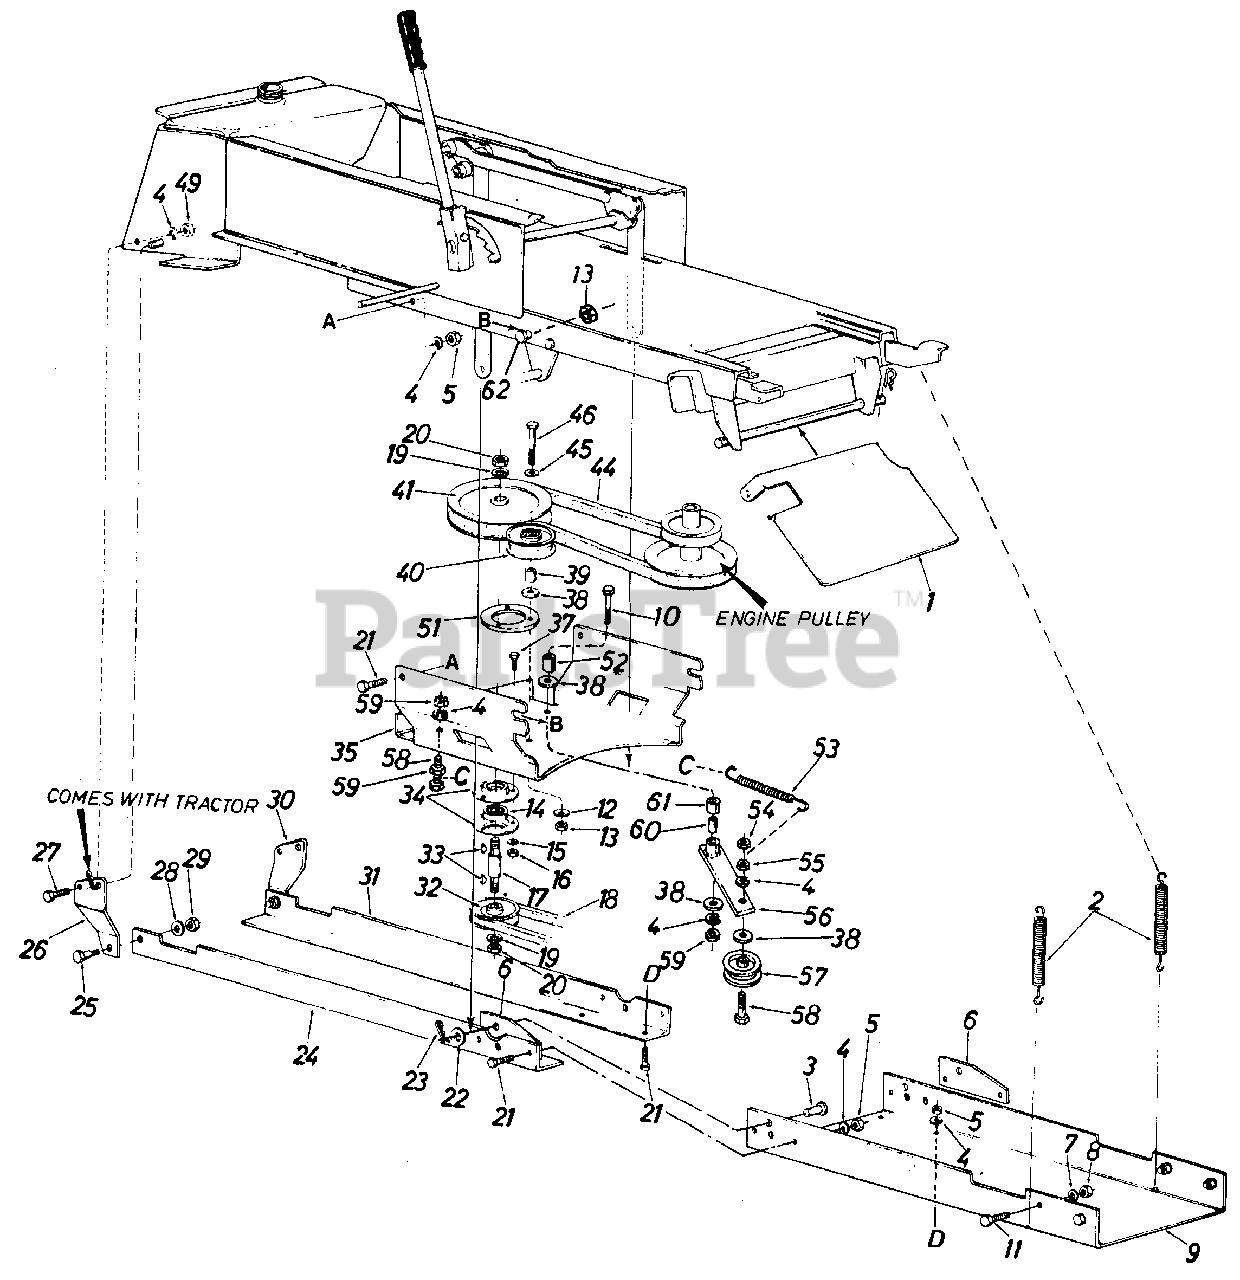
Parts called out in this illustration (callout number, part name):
1	Guide Bracket
2	Helper Spring
3	Clevis Pin
4	L.-Wash. 3/8" I.D.*
5	Hex L.-Nut 3/8-24 Thd.
6	Attaching Plate
7	L.-Wash. 1/2" I.D.*
8	Hex L.-Nut 1/2-20 Thd.
9	Front Support Channel
10	Hex Bolt 3/8-16 x 3 75" Lg.
11	Hek Bolt 1/2-20 x 1.25" Lg.*
12	Belleville Wash. 3/8" I.D.
13	Hex L.-Nut 3/8-16 Thd.
14	Ball Bearing
15	L.-Wash. 5/16" I.D.*
16	Hex Nut 5/16-18 Thd.*
17	Spindle
18	"V"-Belt 1/2" x 85 x 2 (Kevlar)
19	L.-Wash. 5/8" I.D.*
20	Hex Jam Nut 5/8-11 Thd.
21	Hex Bolt 3/8-24 x 1.00" Lg.*
22	Flat Washer
23	Internal Cotter Pin
28	Fl.-Wash. .44" I.D. x 1.38" O.D. x .130
29	Hex L.-Nut 7/16-24 Thd.
30	Rear Hanger Brk't.-L.H.
33	#6 Hi-Pro Key 3/16 x 5/8" Dia.
34	Bearing Housing
35	Supporting Bracket
37	Hex Sems Bolt 5/16-18 x 1.00" Lg.*
38	Fl Wash. .38" I.D. x 1.00" O.D. x .135
39	Spacer .38" I.D. x .62" O.D.
40	Fl.-IdlerPulley
41	Upper Drive Pulley
44	"V"-Belt 1/2" x 49.8" Lg.
45	Fl.-Wash.
46	Hex Bolt 3/8-16 x 2.50" Lg.*
49	Hex Nut 3/8-16 Thd.*
53	Extension Spring .54" O.D. x 5.25" Lg.
54	Hex Cent. L.-Nut 3/8-16 Thd.
55	Hex Jam Nut 5/8-11 Thd.
56	Idler Arm Ass'y.
57	Idler Pulley
58	Hex Bolt 3/8-16 x 2.25" Lg.
59	Hex Jam Nut 3/8-16 Thd.
60	Spacer .377" I.D. x .60" O.D. x .830" Lg.
61	Spacer.380" I.D. x .630" O.D. x .565" Lg.
62	Shld. Bolt .498" Dia. x .340"
